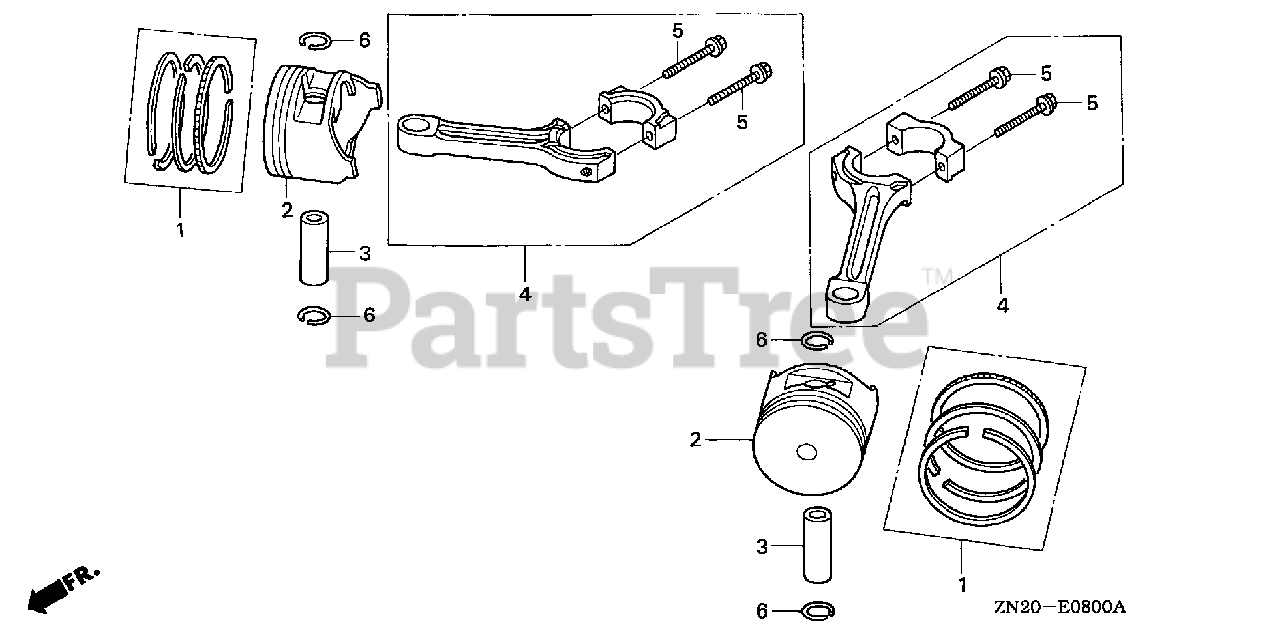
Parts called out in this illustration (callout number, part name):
1	RING SET, PISTON (STD) (NIPPON)
1	RING SET, PISTON (0.25)
1	RING SET, PISTON (0.50)
1	RING SET, PISTON (0.75)
2	PISTON (STD)
2	PISTON (0.25)
2	PISTON (0.50)
2	PISTON (0.75)
3	PIN, PISTON
4	ROD ASSY., CONNECTING
5	BOLT, CONNECTING ROD (6X37)
6	CLIP, PISTON PIN (18MM)
